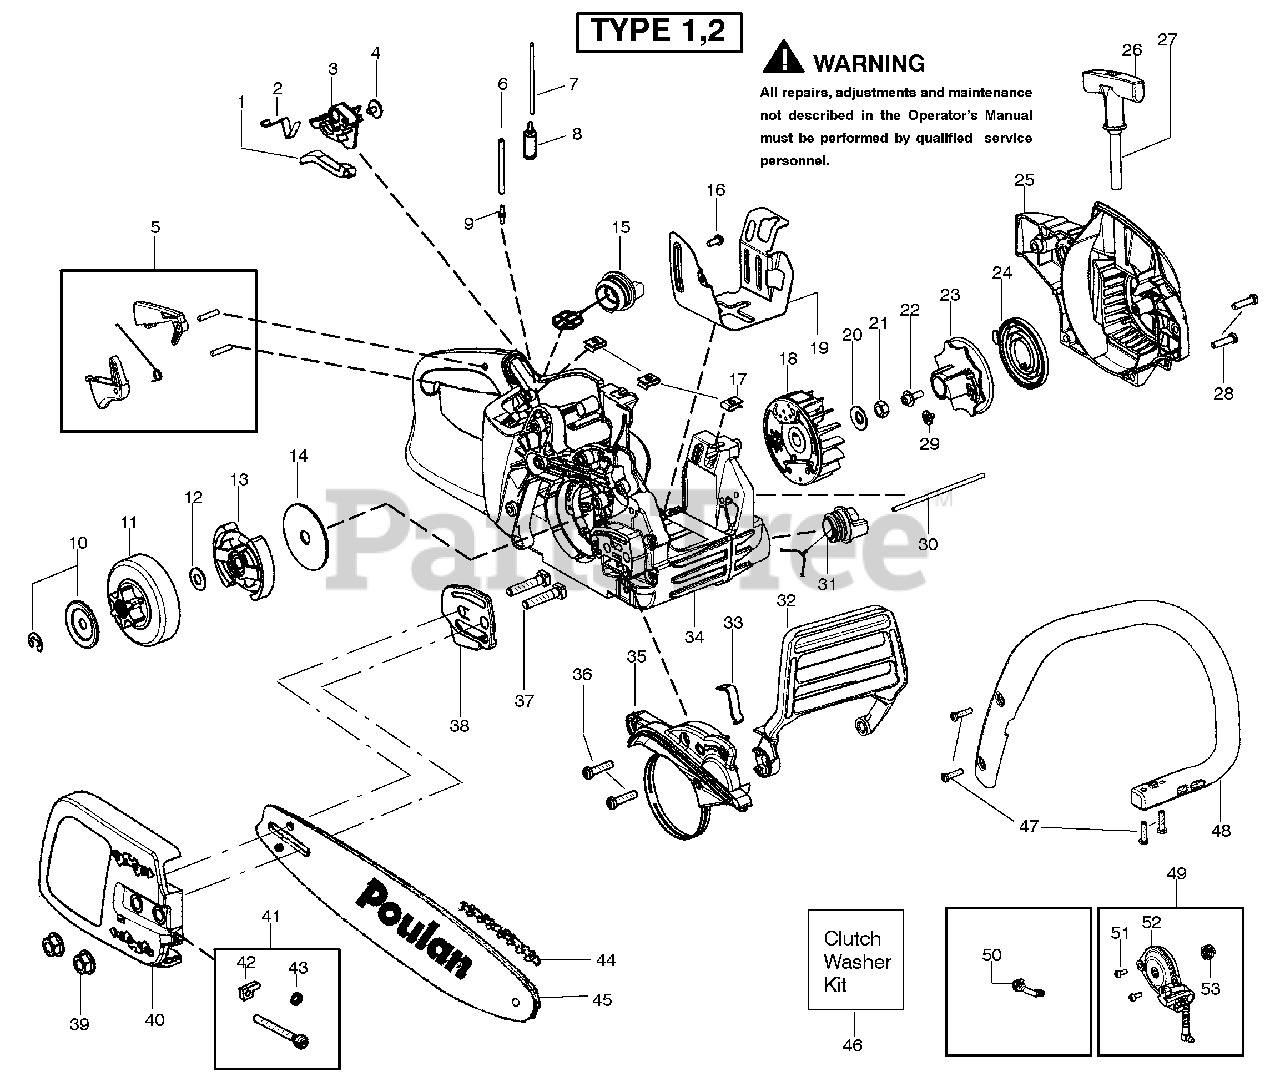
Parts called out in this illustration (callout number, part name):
1	Knob-Choke
2	Spring-Ign. Switch
3	Lever-Ign. Switch
5	Kit-Trigger/Lockout
6	Kit-Fuel Line
7	Kit-Fuel Line
8	Assy-Fuel Pick Up
9	Fitting-Fuel line
10	Kit-Clutch Washer
11	Assy-Clutch Drum 3/8"
12	Kit-Clutch Washer
13	Assy-Clutch
14	Washer-Large Clutch
15	Assy-Fuel Cap w/ret
17	Nut-"U" type Speed
18	Assy-Flywheel
19	Shield-Heat
20	Washer-Flywheel
21	Nut-Flywheel
22	Screw
23	Pulley-Starter
24	Spring-Starter
25	Housing-Fan
26	Handle-Starter
27	Kit-Rope
30	Assy-Oil Vent
31	Assy-Oil Cap w/ret.
32	Handguard
33	Spring-Handguard
34	Assy-Chassis
35	Kit-Chainbrake
37	Bolt-Bar
38	Plate-Bar
40	Assy-Clutch Cover
41	Kit-Bar Adjust
42	Pin-Bar Adjust
43	Retainer-Bar Adjust
44	Accy-14" Chain
45	Accy-14" Bar
46	Kit-Clutch Washer
48	Handle-Front
49	Kit-Oil Pump
50	Assy-Oil Pick Up
52	Assy-Oil Pump
53	Gear-Worm
